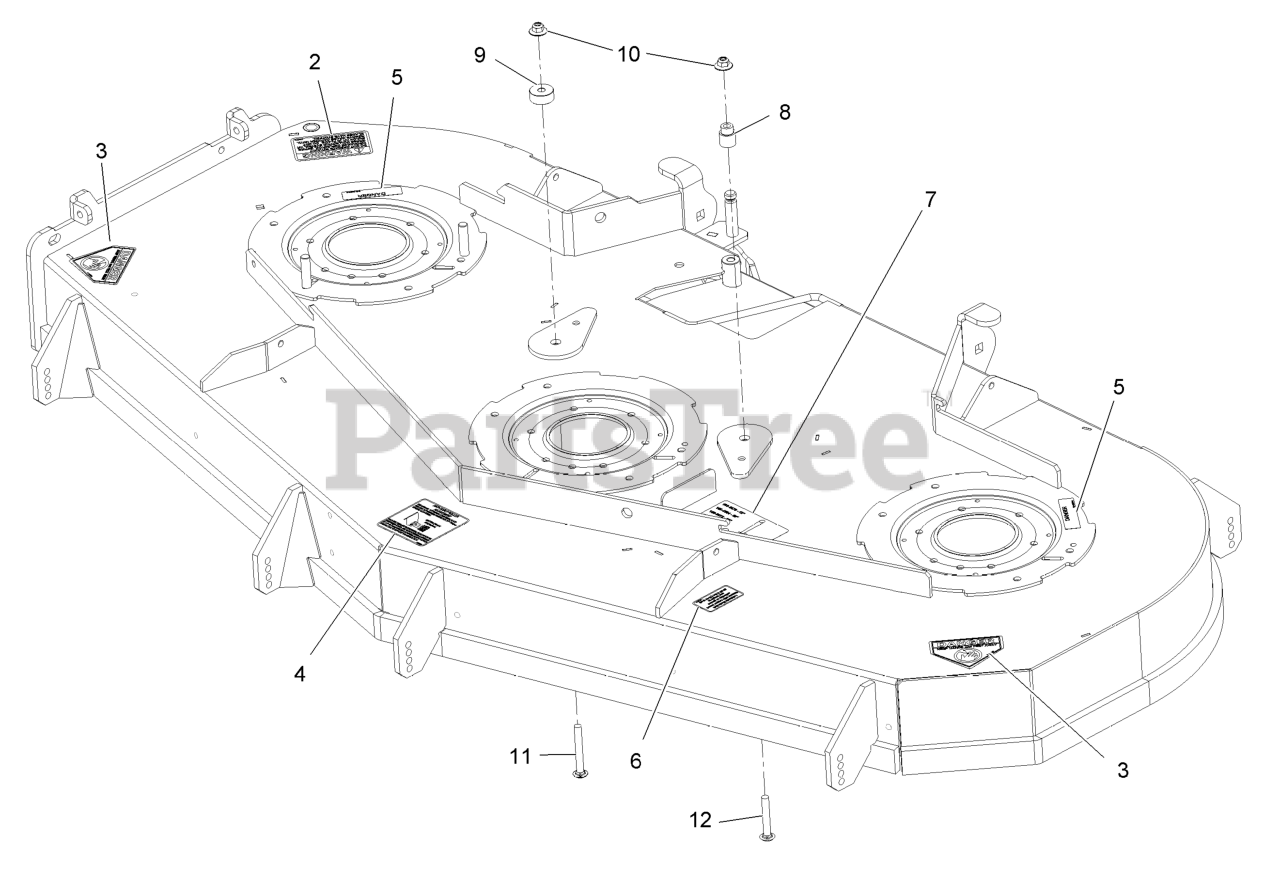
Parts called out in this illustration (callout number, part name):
2	DECAL-WARNING, DISCHARGE
3	DECAL-DANGER
4	DECAL,ANTISCALP
5	DECAL-COVER, MISSING
6	DECAL,BOLT TORQUE
7	DECAL,BELT ROUTING
8	BUSHING-IDLER
9	SPACER-IDLER
10	Nut-Nyloc 3/8-16 Flg
11	SCREW-CARR
12	SCREW-CARR
